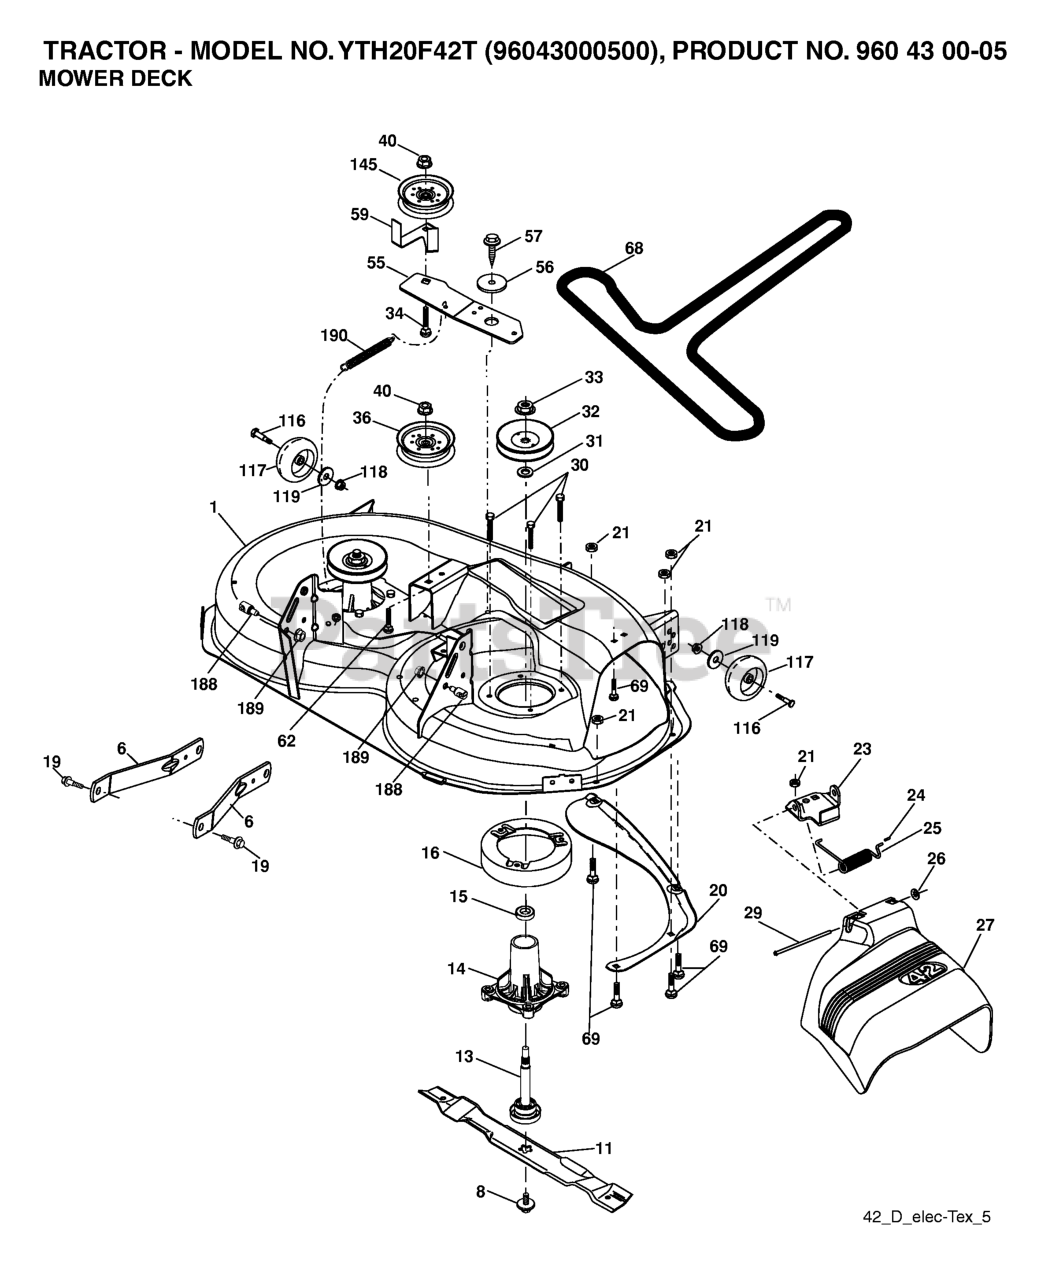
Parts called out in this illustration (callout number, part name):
1	DECK.WELDMENT.42"
6	ARM.SUSPENSION.MOWER.R
8	BOLT.WASHER.ASM.7/16-2
11	BLADE.42"MULCH.PREMIUM
13	SHAFT.ASM.MDRL.N/GREASE.38
14	MANDREL.ASM.SUB-NON.GR
16	STRIPPER.MANDREL.ROUND.BLACK
19	BOLT.SHOULDER
20	BAFFLE.VORTEX
21	LOCKNUT
23	BRKT.DEFLECTOR.38"2005+
24	CAP-SLEEVE LT
25	SPRING.TORSION.DEFLECT
26	NUT PUSH M
27	SHIELD.DEFLECTOR.MOWER.42"BLAC
29	ROD.HINGE
30	SCREW, WASHER HEAD
31	WASHER.SPACER.MANDREL
32	PULLEY MANDREL
33	NUT.FLANGE.LOCK.TOP
34	BOLT.3/8-16X1.50
36	PULLEY.IDLER.2006
40	NUT LOCK FLG 3/8-16 UNC
56	SPACER.RETAINER
57	SCREW 3/8-16X1
59	GUARD TUV IDLER
68	BELT V SECONDARY
69	BOLT
116	SHOULDER BOLT
117	RP WHEEL. GUAGE RALLY
118	LOCKNUT
119	WASHER.5/16.FLAT.STE.STD.
145	PULLEY.IDLER.FLAT
188	STUD.FASTNER.W/ANTI-ROTATE
189	NUT LOCK HEX FLANGE 5/16-18
190	SPRING.MOWER.DRIVE.ELECTRIC
